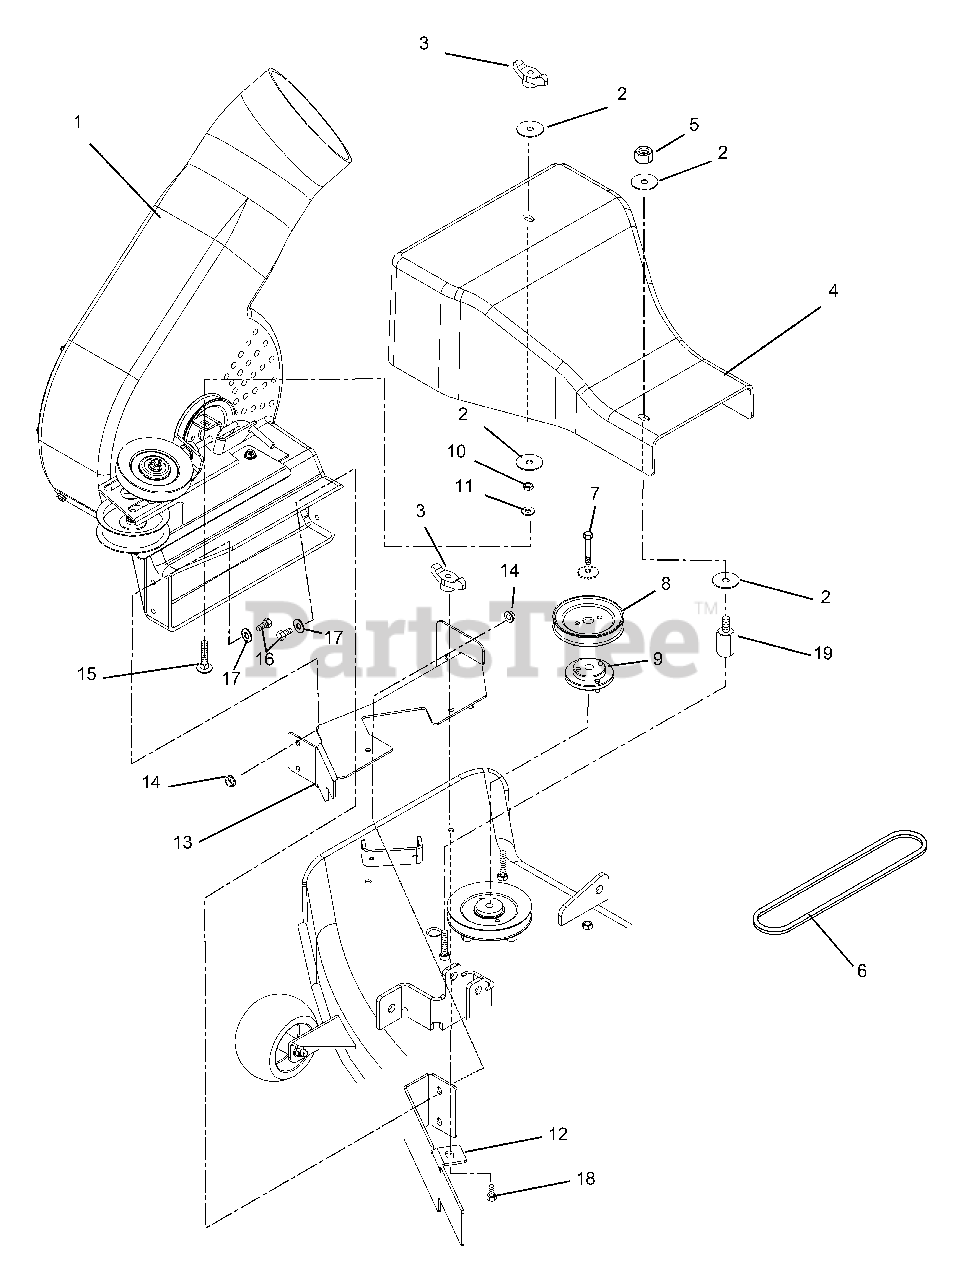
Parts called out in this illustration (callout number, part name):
1	BLOWER HSG W/DECAL
2	WSHR-FL-STL .380X1.50X.062 YWZ
3	KNOB - WING .312-18 UNC
4	COVER, 40" ZOOM BAGGER
5	@NUT-LK-CTR .31-18 YWZC
6	BELT,HA WRAPPED
7	BLT-HEX .38-16X1.75 GR8 M-EPYZ
8	SHEAVE, 4.00 DIA.
9	ASSEMBLY, SHEAVE ADAPTER
10	NUT- JAM .312-18 YWZC
11	@WSHR-FL-STL.312X.734X.065 YWZ
12	BAFFLE, 40 ZOOM BAGGER
13	WMT, BLOWER BRKT (40 ZOOM)
14	@NUT-LK-NYL-FLG .25-20 YWZC
15	@BLT-RDHDSQNK .31-18X1.50 G5YZ
16	@BLT-HEX .25-20X1.00 GR5 YWZC
17	@WSHR-FL-STL.281X.62X.065 YWZC
18	@BLT-HEX .31-18X1.00 GR5 YWZC
19	STANDOFF, 2.75 X 5/16-18
